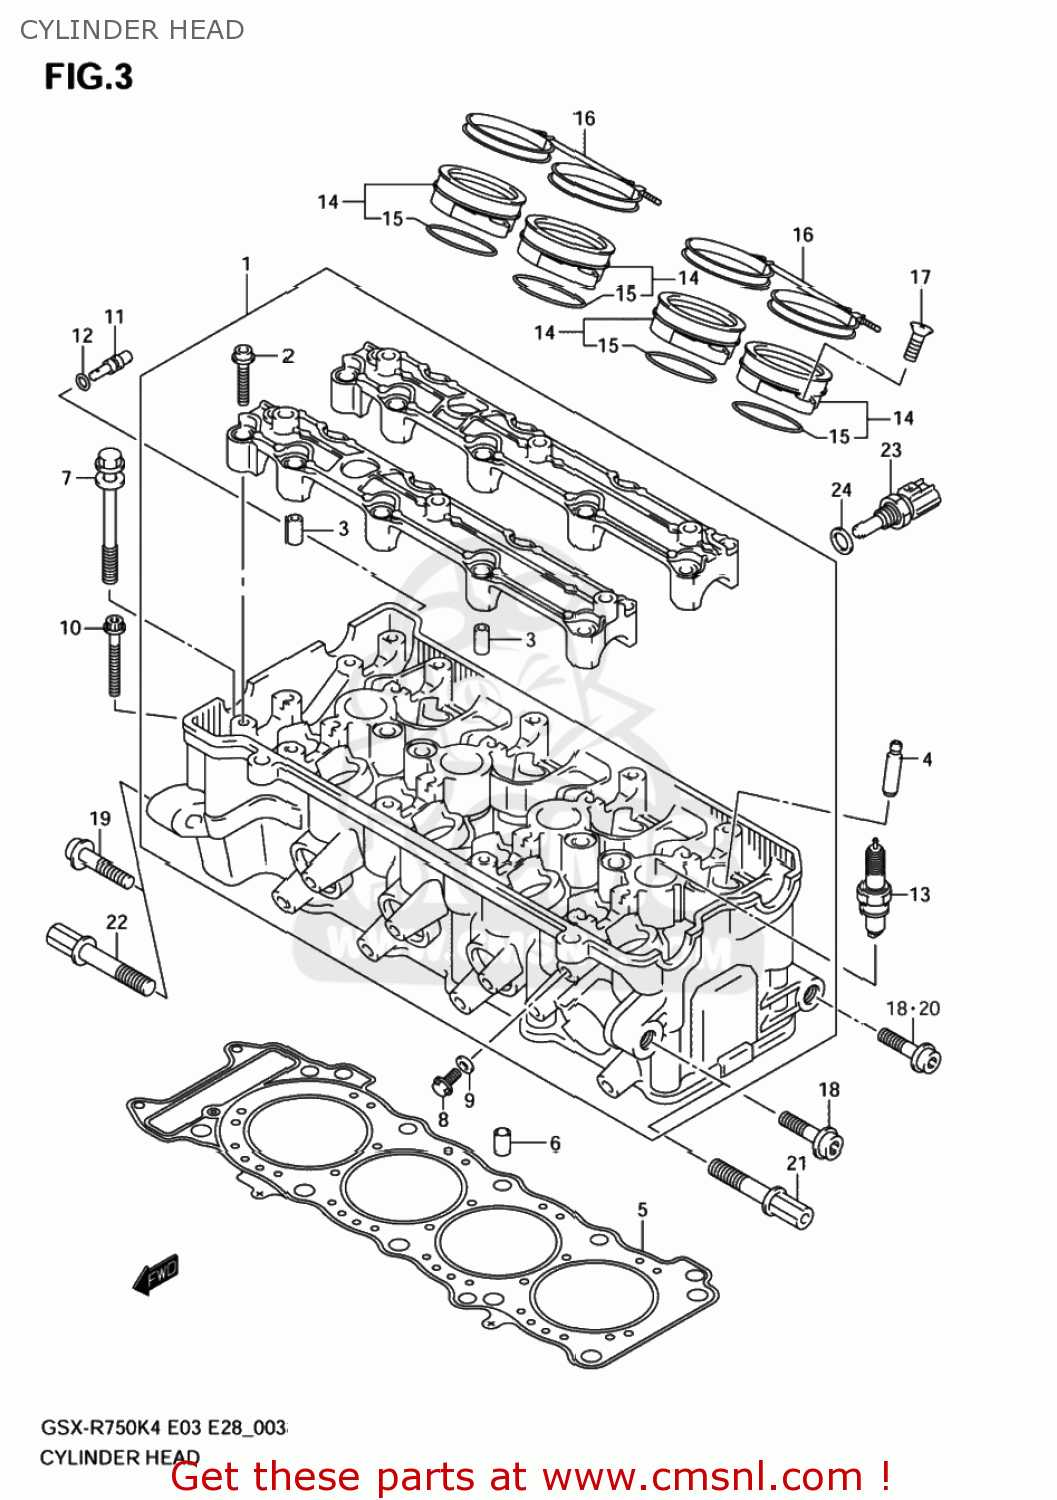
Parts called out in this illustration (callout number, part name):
1	HEAD ASSY,CYLINDER
2	BOLT(6X40)
3	PIN(6.2X8X16)
4	GUIDE,VALVE(OS:0.3)
5	GASKET,CYLINDER HEAD (NAS)
6	PIN
7	BOLT,CYLINDER HEAD(L:105)
8	BOLT(6X12)
9	GASKET(5.8X13X1.2) (NAS)
10	BOLT,CYL.OIL P
11	JET(8)
12	O RING(D:1.2,ID:4)
13	PLUG,SPARK(CR8E)
14	PIPE ASSY,INTAKE
15	O RING(D:2.4,ID:47X42)
16	CLAMP COMP,INT
17	SCREW ,6X16
18	BOLT(10X45)
19	BOLT(10X55)
20	BOLT(10X45)
21	BOLT,ENGINE MOUNTING HEAD
22	BOLT,ENGINE MOUNTING HEAD
23	SENSOR,WATER TEMP
24	GASKET(12X17X1) (NAS)
